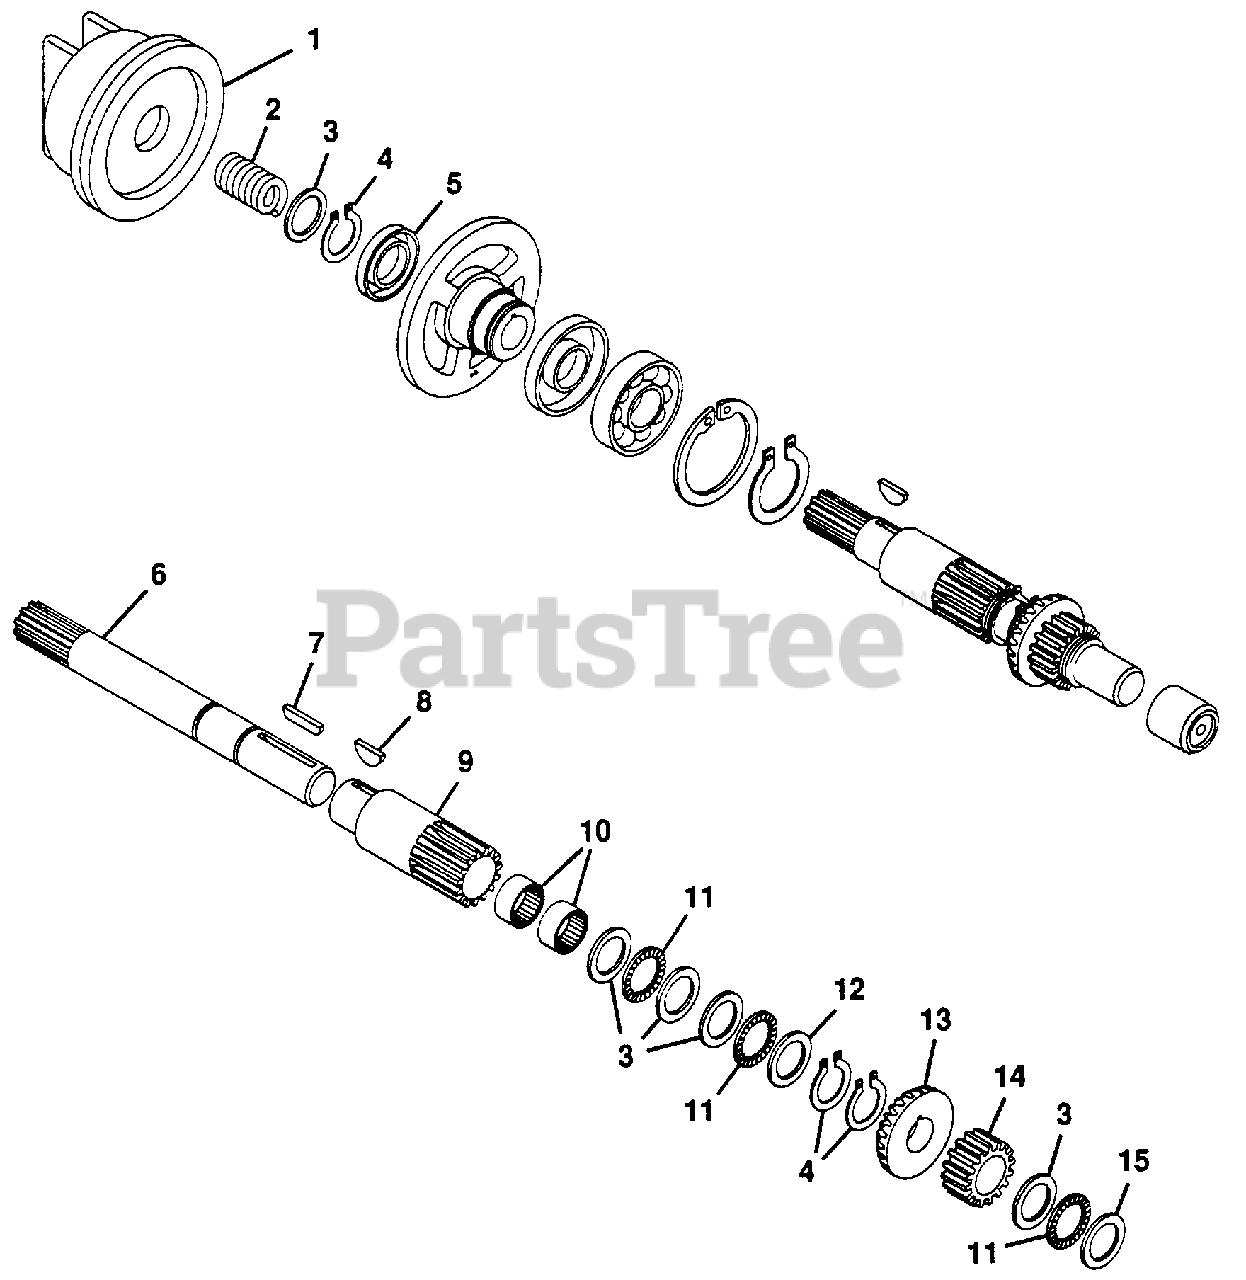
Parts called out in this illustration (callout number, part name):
1	Number 11 - Fwd-Rev Clutch Asm.
2	Spring, Comp. 1.0x.80x36 lb/in
3	Race, Brg Thrust .752x1.240x.030
4	Ring, Retaining .750 Shaft
5	Seal, Oil .750x1.625x.250
6	Shaft, Fwd Clutch
7	Key, Woodruff .188x1.25 Hrd #19
8	Key, Woodruff .188x.625 Hrd #61
10	Bearing, Needle .75x1x.50
11	Bearing, Thrust .752x1.240x.078
12	Race, .060 Bearing Thrust
13	Gear, Bevel
14	Gear, 10 DP 16 Teeth x .750 Std.
15	Race, Thrust .752x1.240x.095
